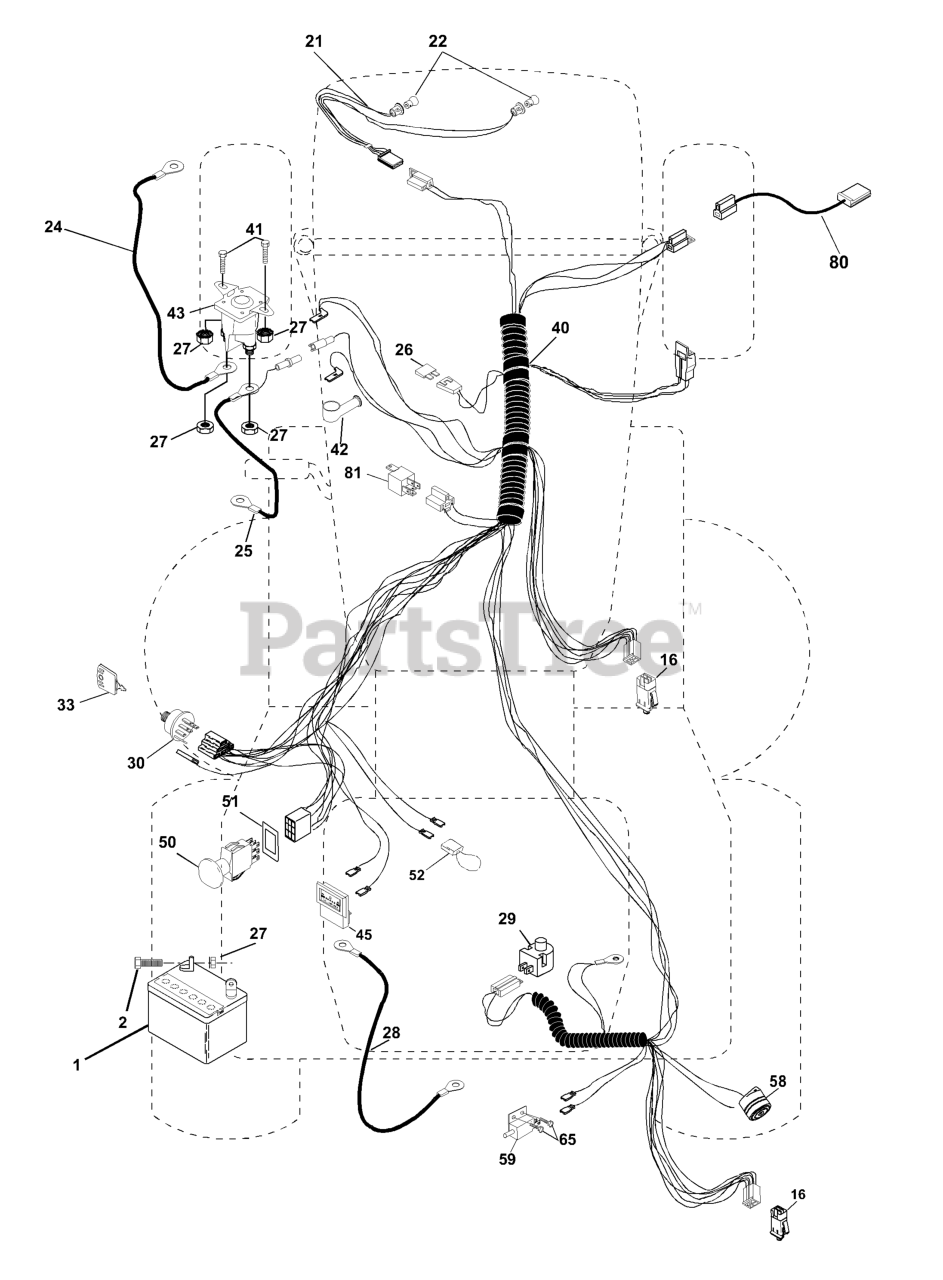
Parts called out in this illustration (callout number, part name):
1	BATTERY 12 VOLT 25 AMP
2	BOLT
16	SWITCH INTERLOCK
24	BATTERY CABLE GT
25	CABLE BATTERY
26	FUSE 15 AMP
27	NUT
28	CABLE GROUND
29	PLUNGER SWITCH (COLOR:OLIVE)
30	SWITCH IGN
33	KEY MLD GEN DELTA
40	HARNESS.ING.CRD.ELECT
41	BOLT
42	TERMINAL COVER
43	SOLINOID
50	PTO SWITCH
51	FRAME RETAINING RING
53	WIRE PROTECTION LOOP
58	BUZZER
65	SCREW
66	SCREW
80	HARNESS, CLUTCH
81	RELAY.ASSY.T
